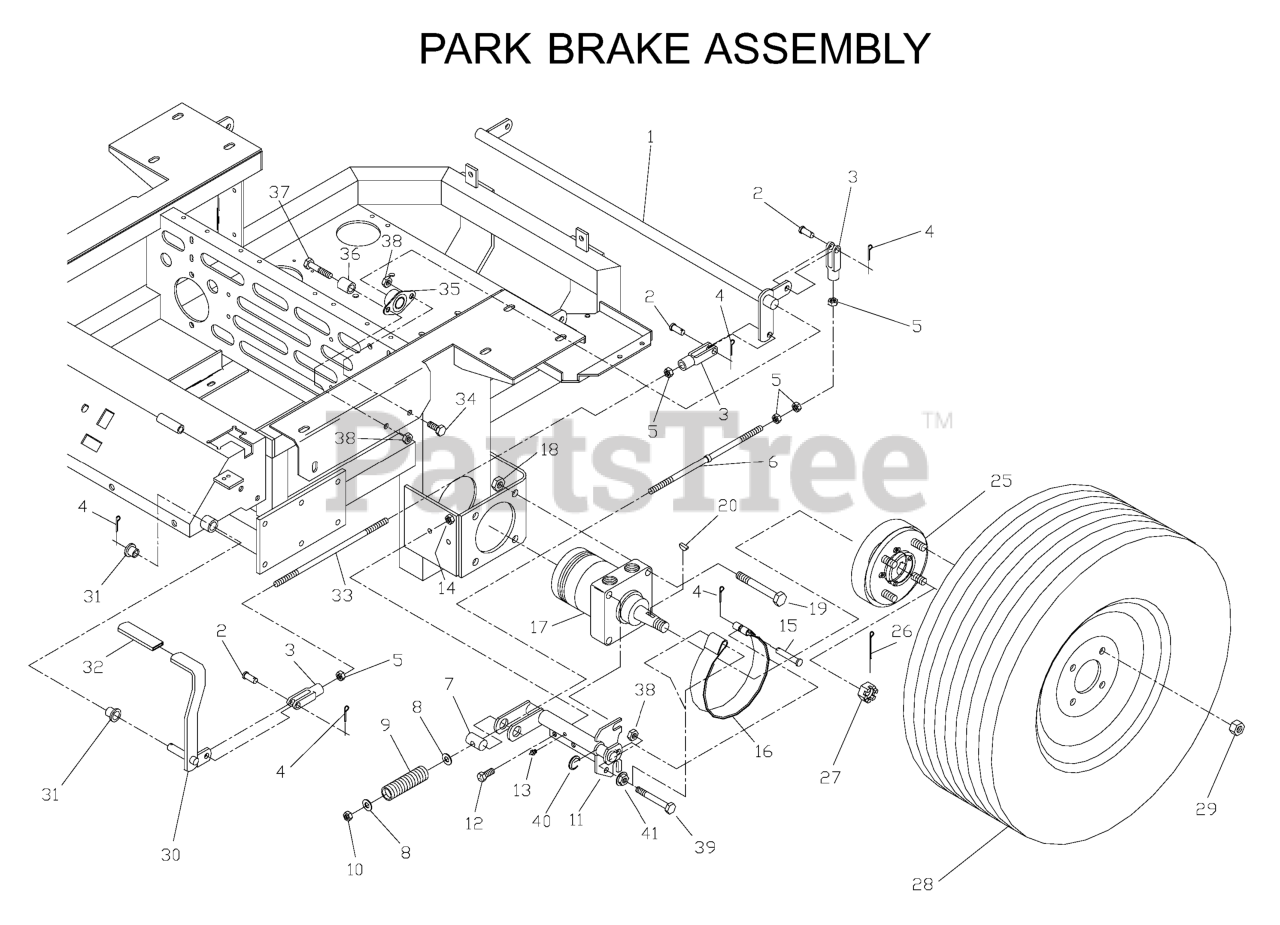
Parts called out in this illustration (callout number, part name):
1	BRAKE SHAFT
2	CLEVIS PIN 3/8 X 1 1/8
3	YOKE-3/8-24 PLTD
4	RP_COTTER PIN 1/8 X 3/4
7	TRUNION PIN
8	WASHER 3/8 FLAT
9	COMPRESSION SPRING
10	NUT 3/8F CENTERLOCK
11	BRAKE BRACKET, LEFT
12	HCS 5/16C X 1
13	ZERK
14	NUT 5/16C CENTERLOCK
15	CLEVIS PIN, 3/8 X 1 1/2
16	BRAKE BAND
17	WHEEL MOTOR
18	NUT 1/2-13 HEX NYLOC ZD
19	HCS 1/2C X 2 3/4
20	KEY, #808 WOODRUFF
25	HUB W/BRAKE DRUM
26	COTTER PIN
27	NUT 3/4-16 HEX SLTD GR5 ZD
28	WHEEL ASSEMBLY
29	LUG NUT 1/2F
30	BRAKE LEVER
33	BRAKE ROD, LONG
34	SCREW 3/8C X 3/4 HEX CAP
35	FLANGE BEARING
36	BUSHING, SLEEVE
37	HCS 3/8C X 2
38	NUT 3/8C CENTERBLOCK
39	HCS 3/8C X 2 1/2
40	E RING 3/4
41	NUT 3/8C WHIZ
539102736	TIRE
539103579	BRAKE BRACKET, RIGHT
539104583	RIM 8.5 X 12
539912234	VALVE STEM TR-412
